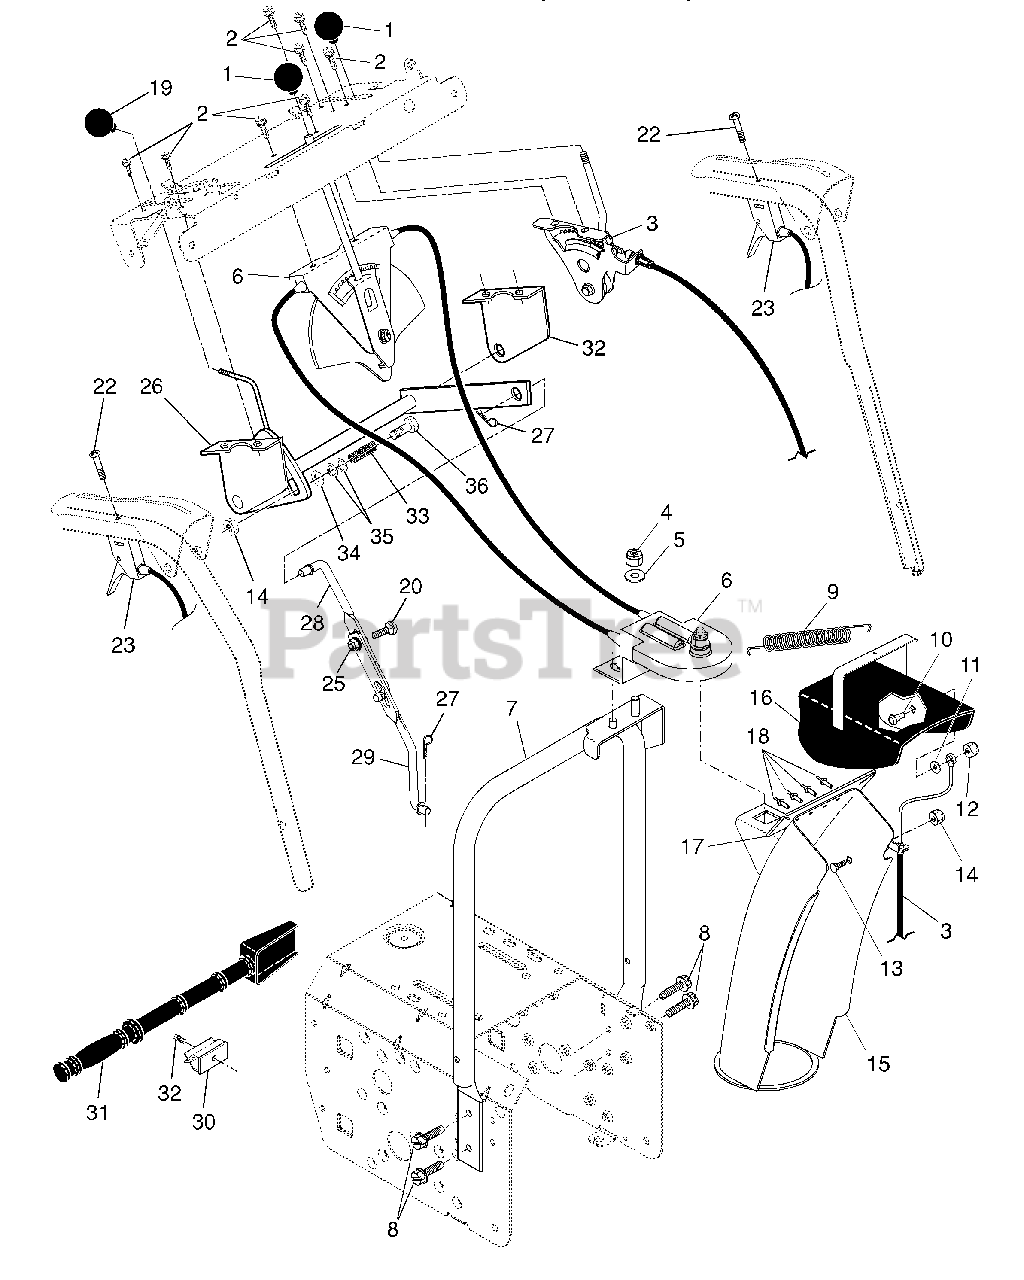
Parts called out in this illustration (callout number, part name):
1	Knob, Lever
2	Screw #10-24 x 5/8
3	Control Assembly, Defl ector
4	Nut, Lock 3/8-16
5	Washer, Flat 3/8
6	Control Assembly, Chute Rotater
7	Support, Pivot
8	Screw, Hex Head 5/16-18 x 3/4
9	Spring, Deflector
10	Bolt, Shoulder
11	Washer, Friction, Nylon
12	Nut, Lock 1/4-20
13	Bolt, Carriage 5/16-18
15	Chute Assembly
16	Deflector Assembly
17	Seal, Deflector
18	Rivet, Blind
19	Knob, Speed Control Lever
20	Bolt, Carriage 5/16-18 x 3/4
22	Screw #10-24 x 1-1/2
23	Control Assembly, Power Steering
25	Nut, Lock 5/16-18
26	Lever Assembly, Speed Control
27	Retainer, Hairpin
28	Rod, Upper, Speed Control
29	Rod, Lower, Speed Control
30	Clamp, Clean-Out Tool
31	Tool, Clean-Out
35	Washer, Friction
